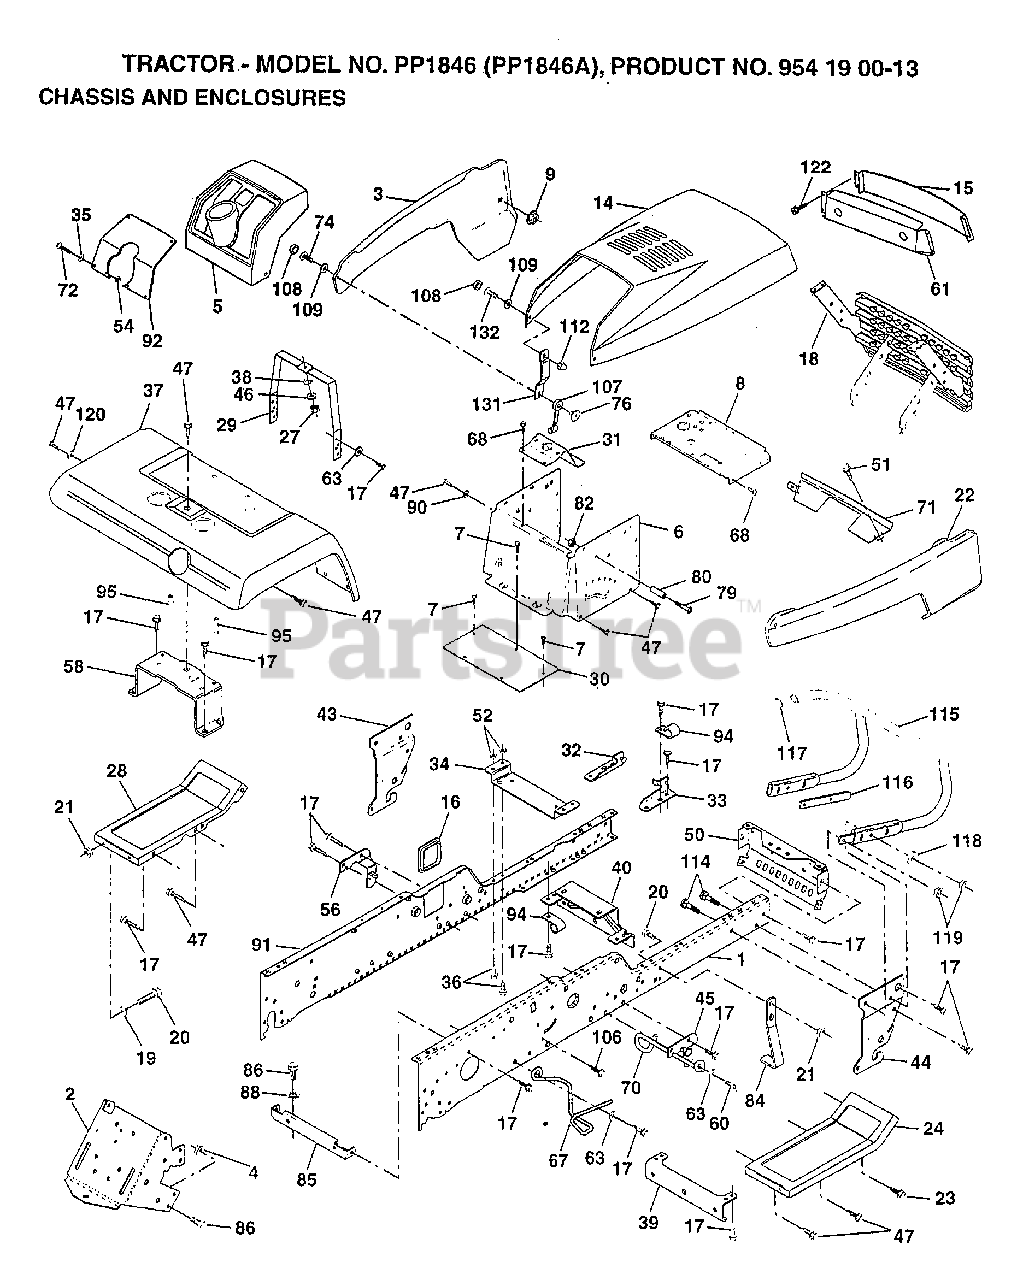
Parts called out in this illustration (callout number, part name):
1	"RAIL,FRAME RH"
2	DRAWBAR GT
3	"PANEL ASM-SIDE,LH"
4	NUT.7/16
5	DASHBOARD BLACK
6	DASH LOWER
7	SCREW
8	SUPPORT.DASH.BTRY
9	PAL NUT LT
14	"HOOD, YARD PRO"
15	LENS.BAR.CLEAR
16	COVER ACCESS
17	SCREW
19	WASHER
20	BOLT
22	"PANEL ASM SIDE,RH"
23	SCREW GTV
24	FOOTREST.RH.LT/GT
28	FOOTREST.LH.LT/GT
29	DASH.SUPT.YP/HUSQ
30	SADDLE.SCR.6SP
31	BRAKET.SUPT.STEER
32	BRACKET ASM FRAME
33	BRACKET ASM FRAME
34	BRACKET.ENG.SUPT.
34	WASHER
36	BOLT
38	LOCKWASHER
39	BRACKET.AXLE.FRT.
40	"BRKT SUPPORT,AXLE"
43	BRACKET.SUS.FT.LH
44	BRACKET.SUS.FT.RH
45	BRACKET.SUSP.RH.
46	WASHER PM
47	SCREW LT
50	"BRKT CHASSIS,FRNT"
51	SCREW CRT
56	BRACKET.SUSP.LH.
58	BRKT.ASM.FENDER
60	SCREW
61	BEZEL.ASM.
63	WASHER
67	"GUIDE BELT, T/A"
68	SCREW LT
70	GUIDE.BELT.MID.SP
71	STRAP.GRILL
72	SCREW
74	SCREW
76	WELDNUT
79	SCREW
80	SPACER LT
84	STOP.OVER.CENTER
85	BRACKET.SUPT.TRAN
86	BOLT
88	LOCKWASHER
90	LOCKWASHER
91	"RAIL FRAME,LH"
92	PLATE, SILKSCREEN DASH
94	CLIP GTV
95	NUT-PUSH YT
107	HOOD LATCH T
108	SNAP CAP LT
109	WASHER LT
112	ACORN NUT RB
114	BOLT.3/8-14X1.25
115	BUMPER.ASM
116	BRACKET.EXT.BUMP.
117	PLUG.PLASTIC
118	WASHER
120	WASHER HYT
131	BKT.SPT.HOOD/PANL
132	SCREW.10-24X3/8.
